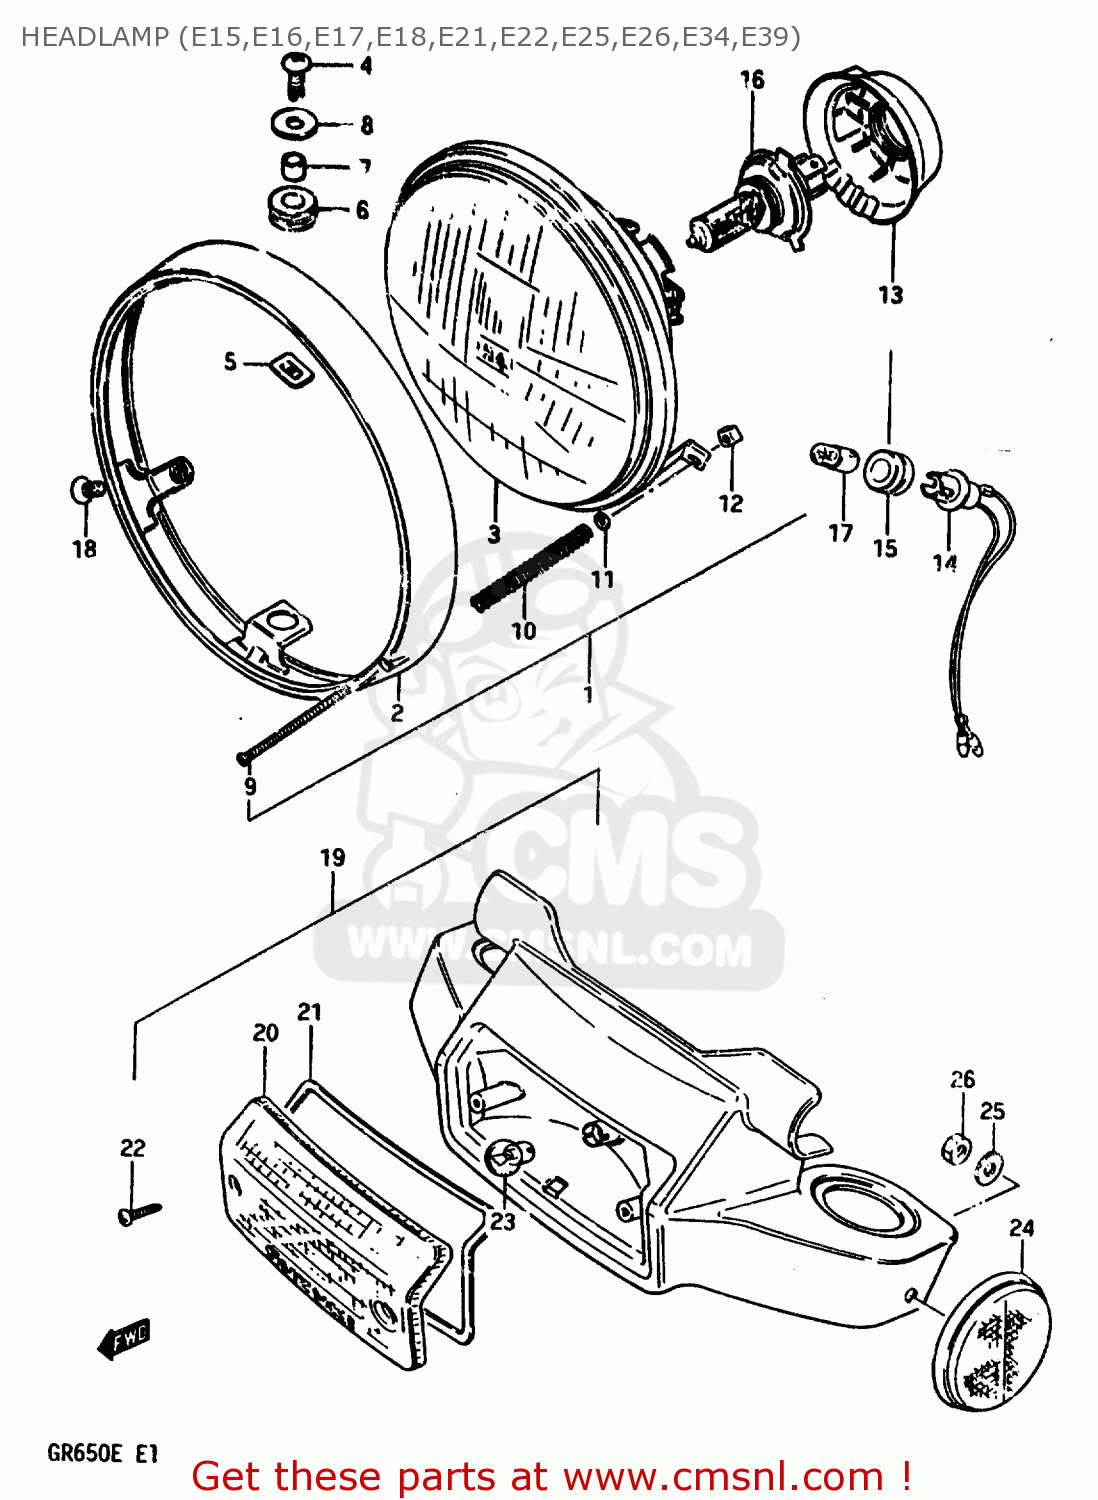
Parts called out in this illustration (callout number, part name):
1	HEADLAMP ASSY
2	RIM,HEAD LAMP
3	UNIT
4	SCREW(5X14)
5	NUT
6	CUSHION
7	SPACER
8	WASHER
9	SCREW,HEADLAMP ADJUST
10	SPRING,HEADLAMP ADJUST
11	WASHER
12	NUT
13	COVER,SOCKET
14	SOCKET
15	JOINT,RUBBER
16	BULB(12V60/55W,H4)
17	BULB(12V4W)
18	SCREW(5X12)
19	LAMP ASSY, FRONT POSITION
20	LENS
21	GASKET,POSITION LAMP
22	SCREW,POSITION LENS
23	BULB(12V4W)
24	REFLEX REFLECTOR ASSEMBLY
25	WASHER
26	NUT
